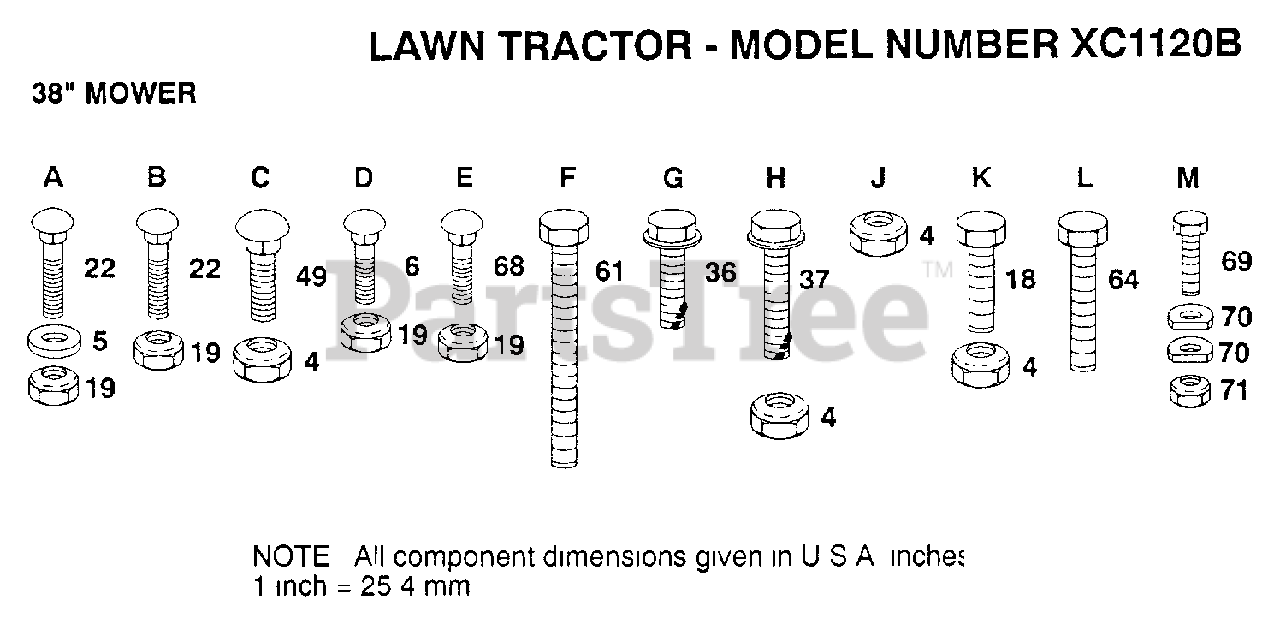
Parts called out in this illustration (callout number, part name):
5	WASHER M
6	BOLT
22	BOLT
36	SCREW
37	SCREW
61	BOLT
64	BOLT.3/8-14X1.25
69	BOLT LT
70	WASHER T
